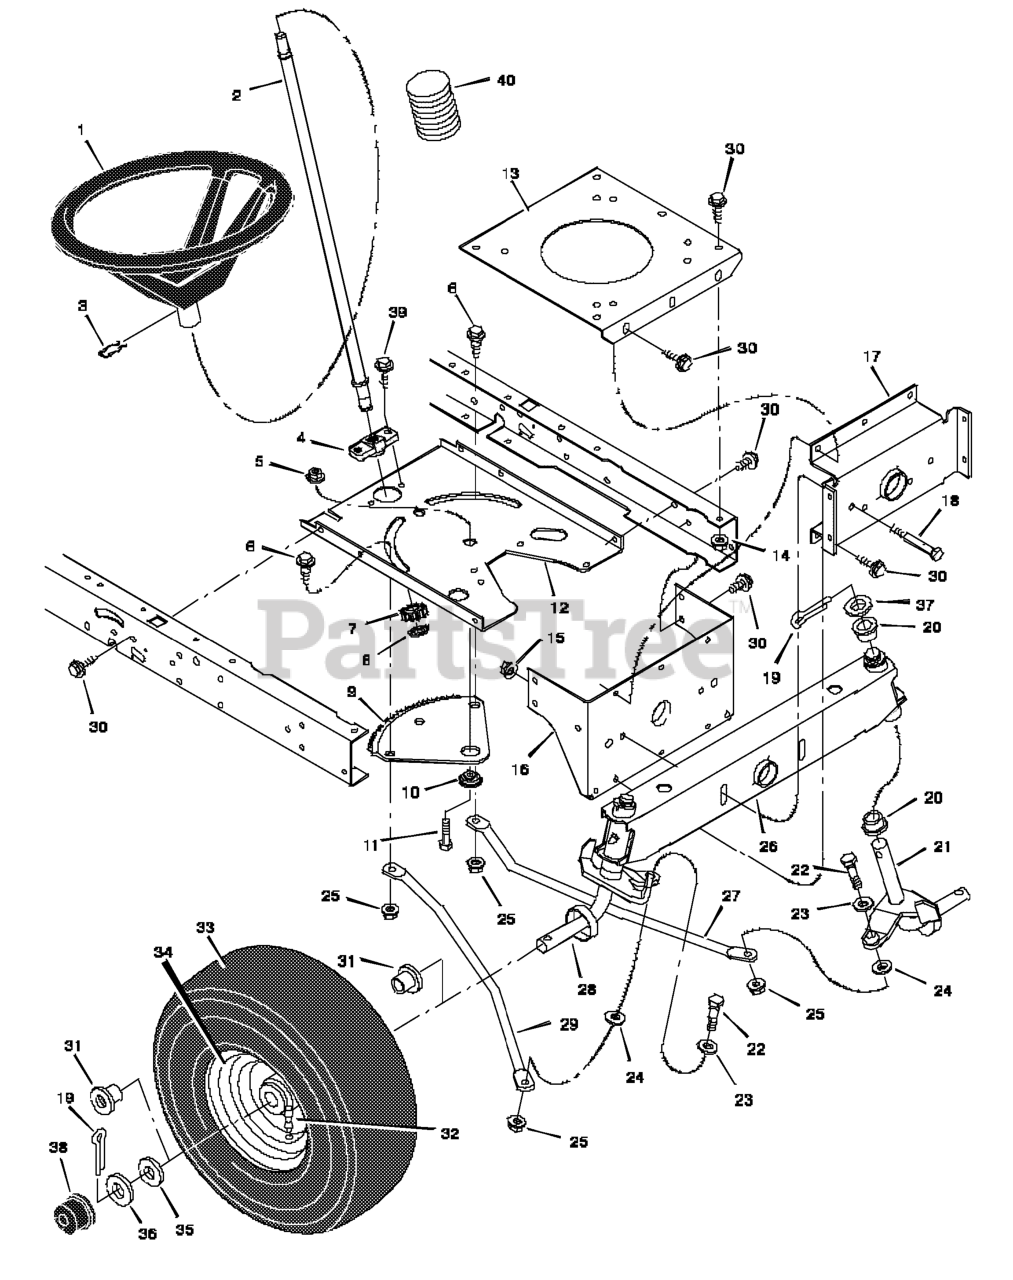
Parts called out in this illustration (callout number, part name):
1	Wheel, Steering
2	Post, Steering
3	Clip, Retainer
4	Bearing
5	Nut, Flange
6	Bolt, Shoulder
7	Gear, Pinion
8	Ring, Snap
9	Gear, Sector
10	Bearing
11	CAPSCREW, Hex Head, 5/16-18 x 1
12	Plate, Steering
13	Plate, Engine
14	Nut, Flange
15	Nut, Flange
16	Bracket, Hanger
17	Axle, Hanger
19	Pin, Cotter
20	Bearing
21	Spindle Assembly, Left
22	Bolt
23	Washer
24	Washer
25	Nut, Flange
26	Axle Assembly
27	Drag Link, Left
28	Spindle Assembly, Right
29	Drag Link, Right
31	Bearing, Wheel
32	Stem, Valve
34	Wheel and Tire Assembly
38	Hub Cap
40	Bellows
